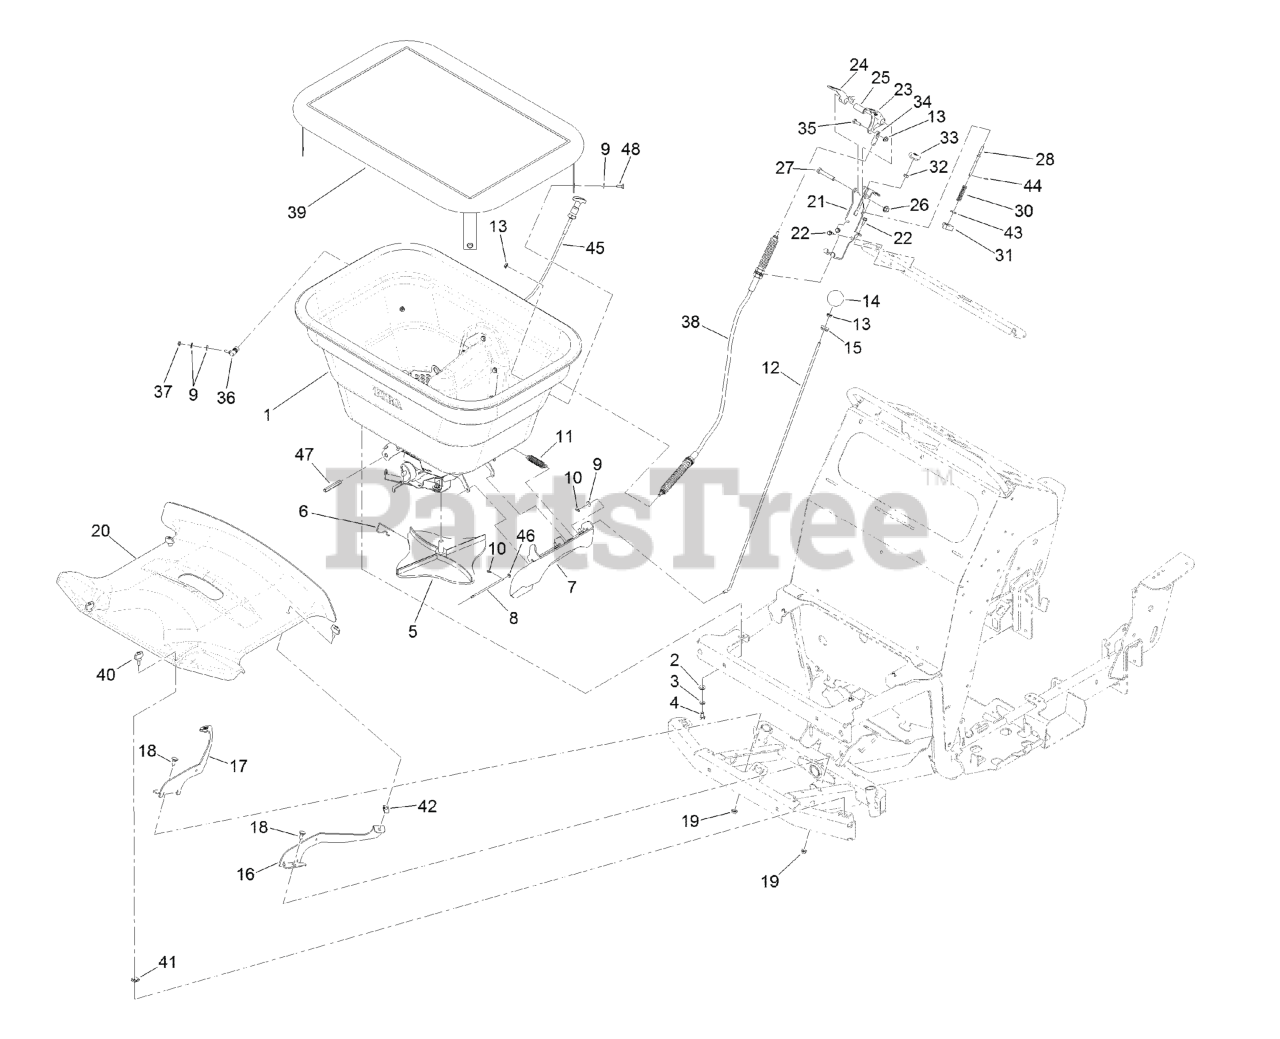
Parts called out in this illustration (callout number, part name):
1	Spreader Hopper ASM
3	WASHER-LOCK
4	SCREW-HH
5	SPINNER-SPREADER
6	CLIP-SPINNER
7	Side Deflector ASM
8	PIN-DEFLECTOR SS
9	WASHER-FLAT
10	PIN-COTTER, HAIR
11	SPRING-EXTENSION
12	ROD-CONTROL, DEFLECTOR
14	KNOB-RATE, FLOW
15	GROMMET
16	BRACKET-COVER, FRONT (LH)
17	BRACKET-COVER, FRONT (RH)
18	SCREW-CARR
20	COVER-FRONT, SPREADER/SPR
21	MOUNT-HANDLE
22	SCREW-HWH
23	LEVER-SPREAD, WIDE
24	LEVER-SPREAD, NARROW
27	SCREW-HH
28	LINK-ADJUST, NARROW
30	SPRING-COMPRESSION, BAIL
31	STOP-SPREAD, NARROW
32	NUT-COUPLER
34	ROD END-BALL JOINT
35	SCREW-HH
36	BALL-JOINT
37	NUT-HEX, NI
39	COVER-HOPPER
41	NUT-RETAINER, U STYLE
42	NUT-RETAINER
43	WASHER-FLAT
44	PIN-COTTER
45	CABLE-CONTROL, TURN LOCK
46	WASHER-FLAT
47	POST-HEX, DIFFUSER GUIDE
48	SCREW-HH
